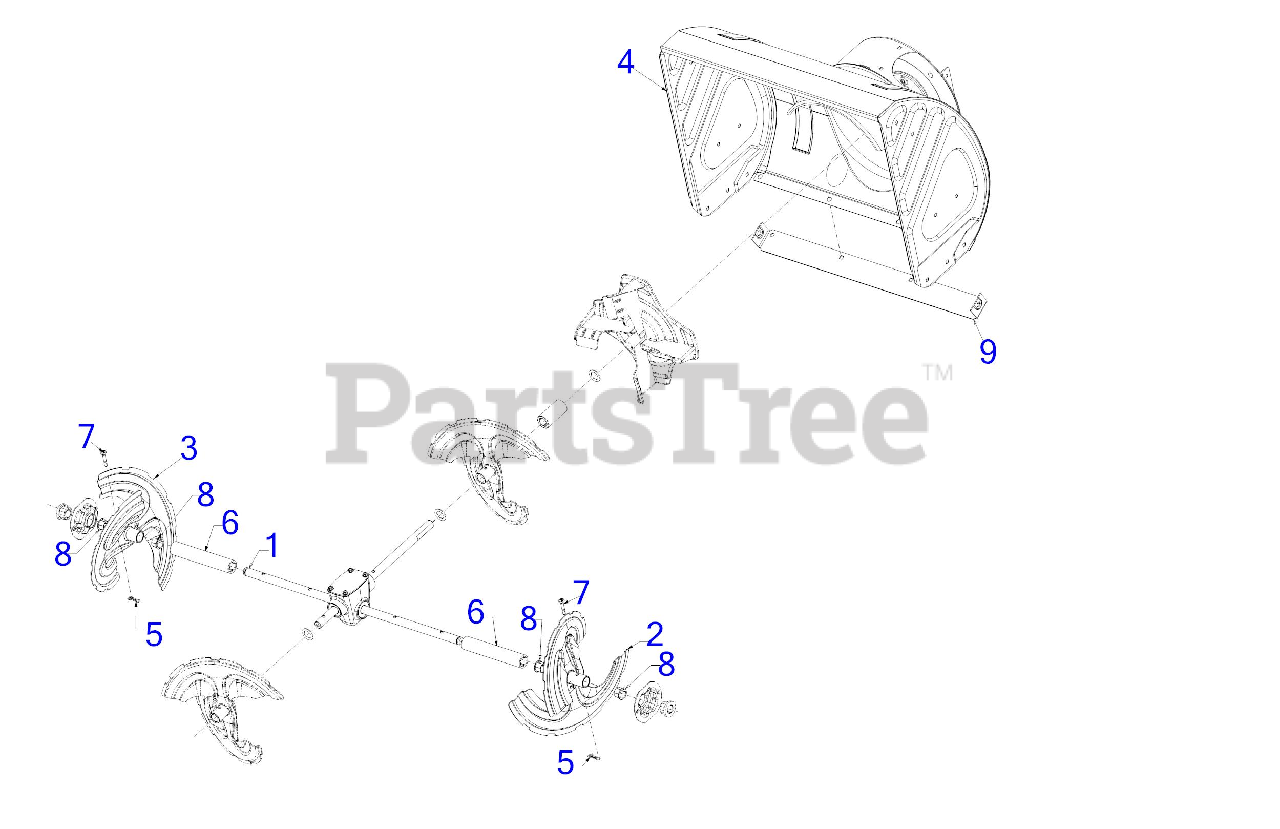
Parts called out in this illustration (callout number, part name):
1	26" AUGER GEARBOX ASSEMBLY
4	26" AUGER HOUSING ASSEMBLY
5	BOW TIE COTTER PIN 1/4-5/16
7	SHEAR PIN .25 X 1.50 (3 STAGE)
8	FLANGE BUSHING
